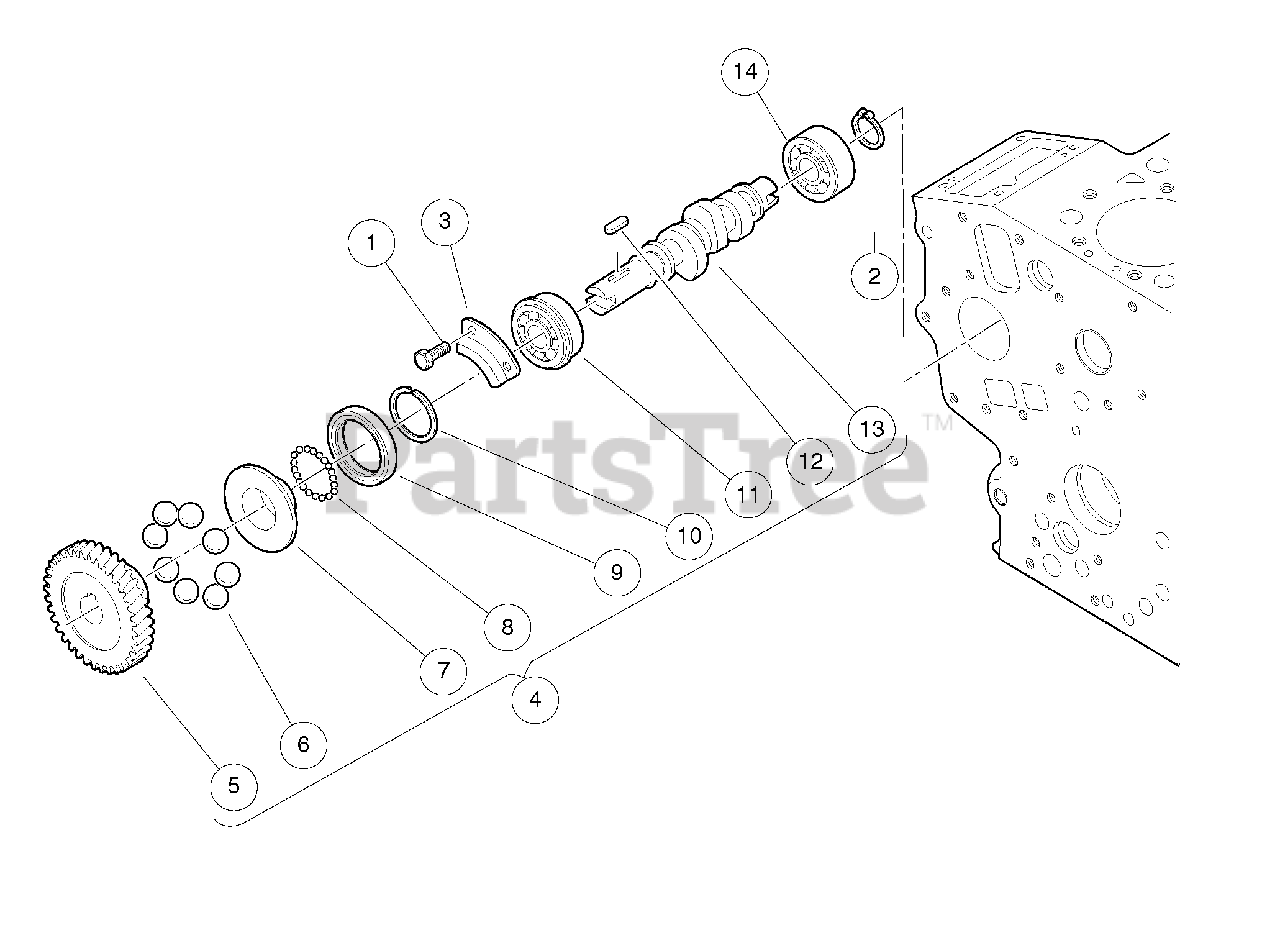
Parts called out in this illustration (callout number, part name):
1	Bolt, D722, Cam End
2	Circlip, External
3	Stopper, Fuel, C/shaft
4	Assy, Fuel Camshaft
5	Gear, Injection Pump
6	Ball, Injection Pump
7	Sleeve, Governor
8	Ball, Governor
9	Case, Governor Ball
11	Bearing, Ball
12	Key, Feather, Short Camshaft
13	Camshaft, Fuel, Short
14	Bearing, Ball
